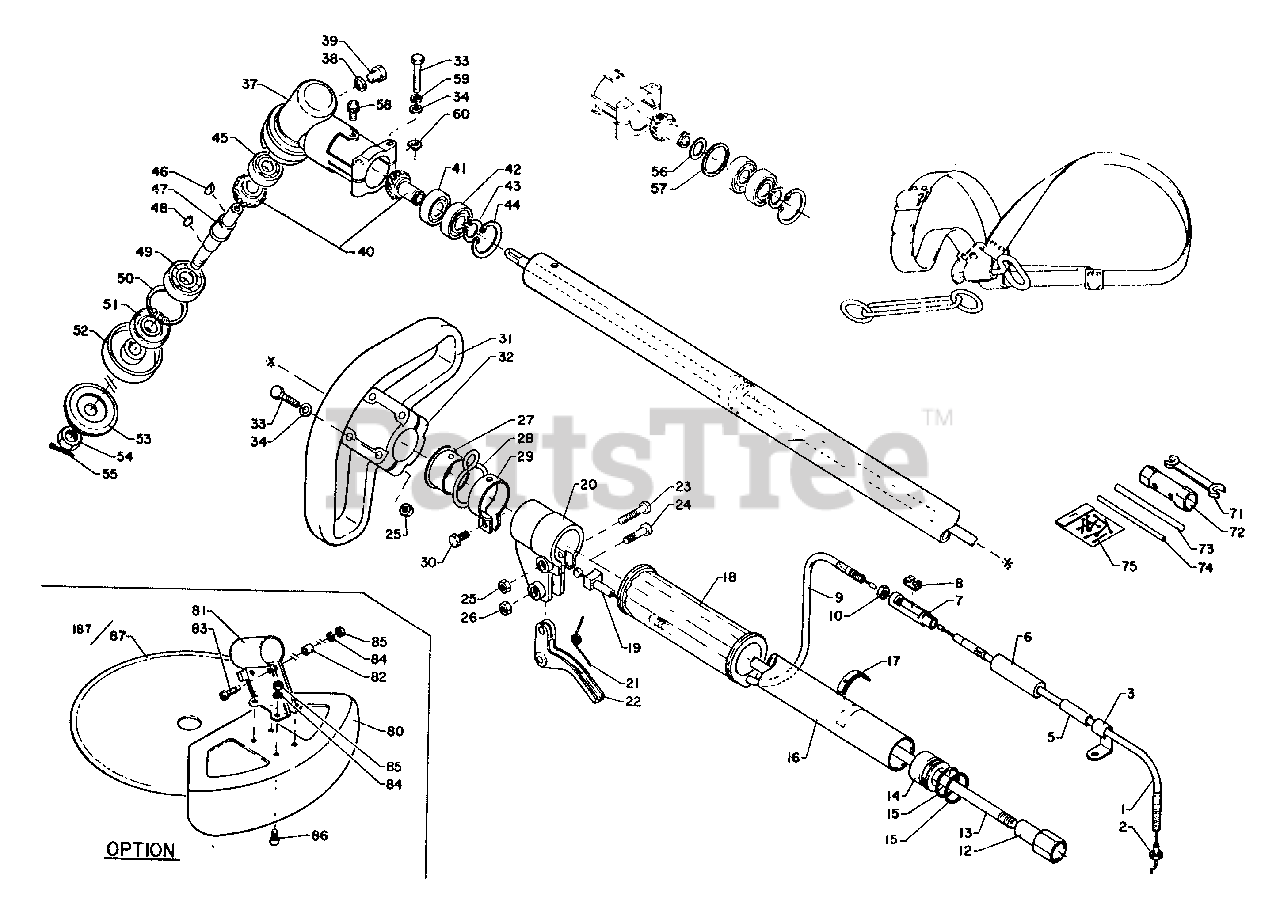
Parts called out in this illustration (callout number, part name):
1	CABLE, THROTTLE
3	CLAMP
7	CONNECTOR, CABLE
8	CONNECTOR
9	CABLE, THROTTLE
10	LOCKNUT - 6
12	CONNECTOR
13	DRIVESHAFT
14	STOPPER
15	O-RING - 22
16	MAIN PIPE ASSY
17	LABEL - ALIGNMENT
18	GRIP
19	GUIDE, CABLE
20	BRACKET, TRIGGER
21	SPRING, TRIGGER
22	TRIGGER, THROTTLE
23	SCREW - 5X28
24	SCREW - 5X30
26	LOCKNUT - 5
27	COLLAR
28	HOOK, SWIVEL
29	HOOK
30	BOLT - 5X10
31	HANDLE
32	BRACKET, HANDLE
33	BOLT - 5X30
34	WASHER - 5
37	CASE, GEAR
38	GASKET
39	BOLT - 8X6
40	GEAR SET
41	BEARING, BALL - 6001
42	BEARING, BALL - 6001
43	RING, RETAINING - 12
44	RING, RETAINING - 28
45	BEARING, BALL - 6000
47	DRIVESHAFT
49	BEARING, BALL - 6201
50	RING, RETAINING - 32
51	SEAL, OIL
52	ADAPTOR, BLADE - UPPER
53	ADAPTOR, BLADE - LOWER
54	NUT - 10 -- LEFT HAND
55	PIN, SPLIT - 2X22
58	SCREW - 5X10
59	LOCKWASHER - 5
71	SPANNER - 8X10mm
72	SOCKET WRENCH - 17X19mm
73	ROD, HANDLE
74	LOCKING TOOL
75	PIN, SPLIT - 2X22
80	SHIELD, DEBRIS
81	BRACKET, SHIELD
82	SPACER
83	SCREW - 5X18
84	LOCKWASHER - 5
85	NUT - 5
86	SCREW - 5X8
87	BLADE - 8 TOOTH -- 10" (25cm)
187	SAW, CIRCULAR
